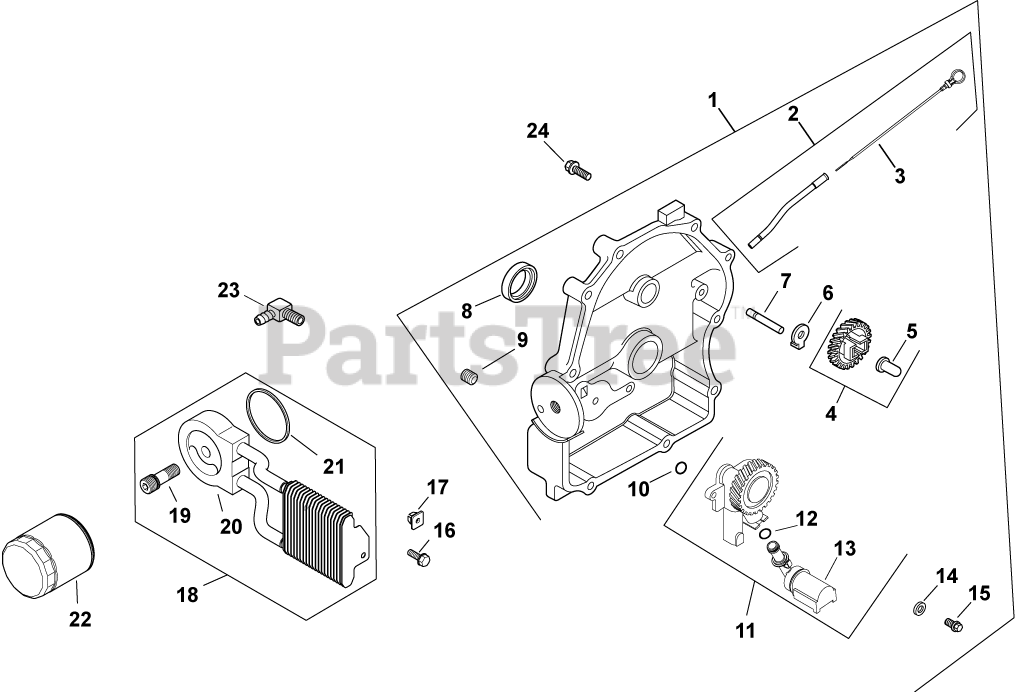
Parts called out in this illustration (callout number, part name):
1	CLOSURE PLATE ASSEMBLY USE 24 009 237-S
2	KIT, DIPSTICK/DIPSTICK TUBES
4	KIT, GOVERNOR GEAR W/PIN
5	PIN, GOVERNOR REGULATING
7	SHAFT, GOVERNOR GEAR
8	SEAL, OIL (KM)-USE 25 032 06-S
9	PLUG, CTSK PIPE 1/8"
11	OIL PUMP ASSY KIT-USE 24 393 53-S
12	O-RING, OIL PICK-UP
13	PICK-UP, OIL
14	WASHER, FLAT 6 MM
15	SCREW,FLG THD FRM M6X1.0X25-(#25086395S)
16	SCREW, TAP M6X1.7X18
17	NUT, PLASTIC (KM)-USE 25 100 37-S
18	COOLER, OIL - PHENOLIC-USE 24 594 36-S
19	NIPPLE, OIL FILTER
20	KIT,OIL FLTR ADPTR (W/DRIP LIP)
21	O-RING, OIL COOLER
22	OIL FILTER
23	CONNECTOR, 90 DEG. HOSE
24	SCREW, FLG M8X1.25X45
